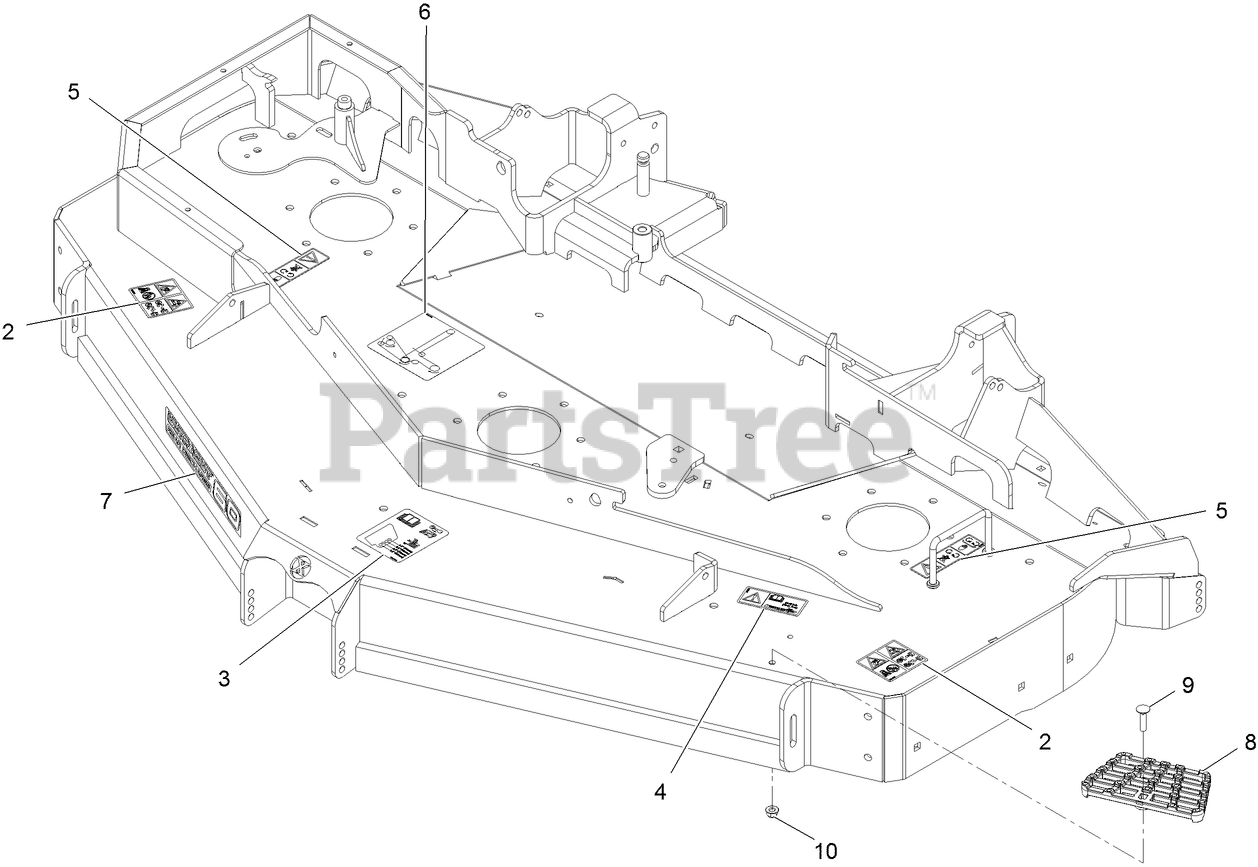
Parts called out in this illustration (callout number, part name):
2	DECAL-DANGER, THROWN OBJECT
3	DECAL-ROLLER, ANTI-SCALP
4	DECAL-TORQUE, BOLT
5	DECAL-COVER, MISSING
6	DECAL-ROUTING, BELT
7	DECAL, 60RD
8	STEP-DECK
9	Bolt-Carriage 5/16-18 X 1 1/4
10	NUT-HF, NI
